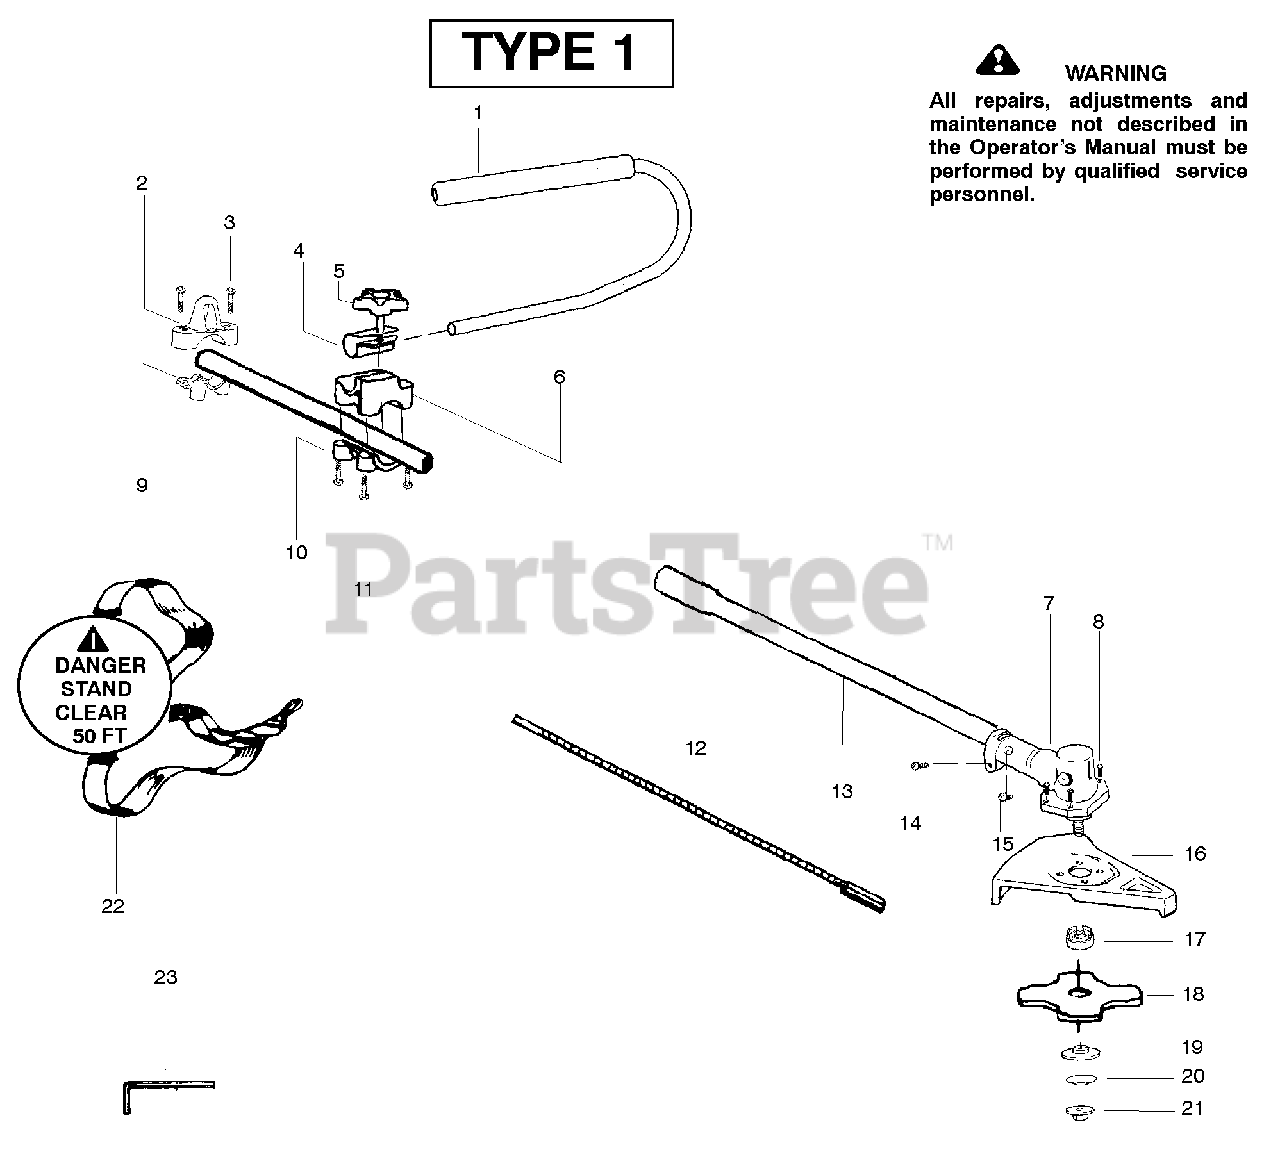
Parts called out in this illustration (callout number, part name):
1	Assy-Handlebar
2	Clamp-Harness Upper
3	Screw
4	Clamp-Handlebar
5	Knob
6	Base-Clamp
7	Kit-Gearbox Assy.
9	Clamp-Harness Lower
10	Kit-Clamp-Tube
11	Screw
12	Flexshaft-Split boom
13	Assy.-Driveshaft
16	Kit-Blade Shield
17	Dust cup - Blade
18	Accy.-Weed Blade (8")
19	Washer-Blade Retaining
20	Washer-Belleville
22	Assy-Shoulder Strap
23	Wrench-Hex (5/32")
